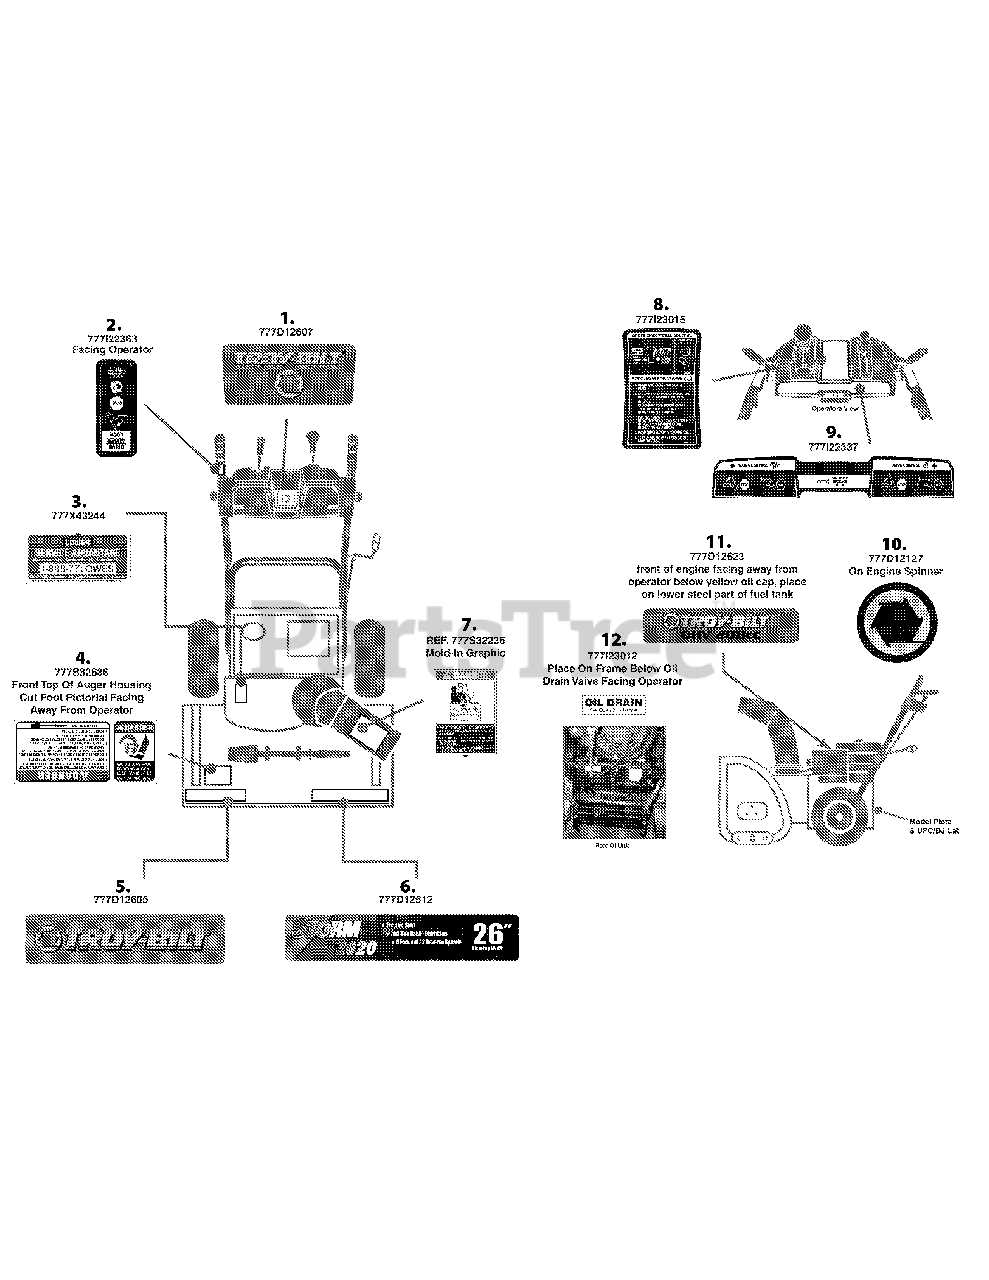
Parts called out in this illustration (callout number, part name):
1	LABEL-SNOW HANDLE 4 STYLE FRONT
2	LABEL-DRV/AUGR LOCK
3	LABEL-LOWES:SERVICELBL
4	LABEL-SNOW HOUSING
5	LABEL-SNOW FRONT LH AUGER TROY
6	LABEL-SNOW FRONT RH AUGER STORM
7	LABEL-SNOW CHUTE
8	LABEL-SNW:P PNL:2-WAY/MNL PTCH
9	LABEL-HANDLE PNL AUGER/DRIVE CTRL
10	LABEL-TILLER MTD ENGINE
11	LABEL-MTD ENGINE TROY
12	LABEL-SNOW OIL DRAIN
